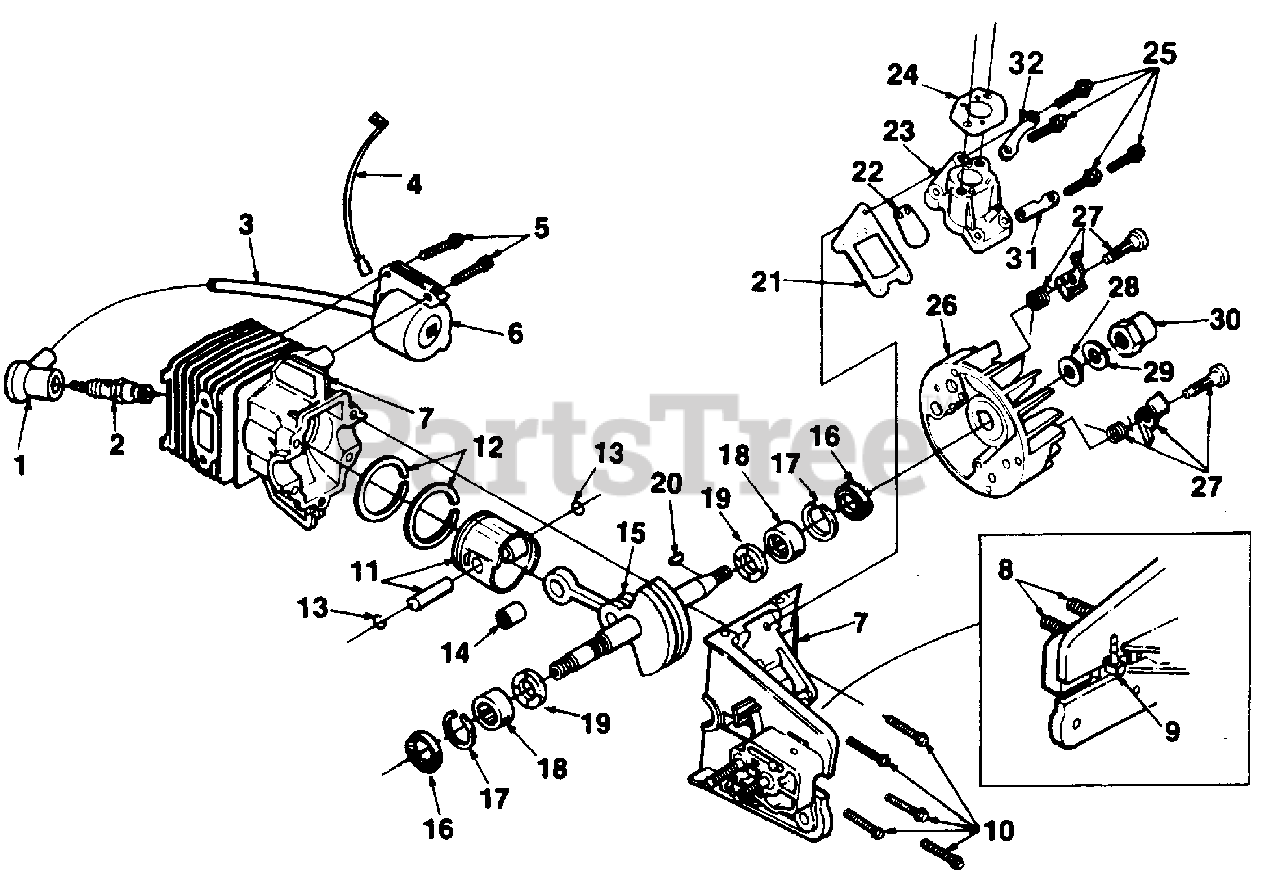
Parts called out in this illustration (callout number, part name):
1	TERMINAL-High tension lead
2	SPARK PLUG (DJ7Y)
3	LEAD- High tension
4	LEAD- Ground
5	SCREW- Mach hex hd. 8-32 x 7/8
6	MODULE Ignition (incl. #1 and #3)
7	CRANKCASE & CYLINDER
8	BOLT- Guide bar
9	FITTING
10	SCREW- 10-24 x 1 1/8
11	PISTON & PIN
12	PISTON RINGS
13	RING- Retaining
14	BEARING- Needle (After Lot #E229)
15	CRANKSHAFT
16	SEAL- Shaft
17	RING- Retaining
18	BEARING- Needle
19	BEARING- Thrust
20	KEY- Magneto
21	GASKET- Manifold
22	REED
23	MANIFOLD- Intake
24	GASKET- Carburetor
25	SCREW- Hex washer 8-32 x 5/8
26	ROTOR- Magneto
27	PAWL- Starter
28	WASHER- Flat 5/16
29	WASHER- Lock 5/16
30	NUT- Guide
31	WASHER- Intake manifold
32	WASHER- Intake manifold
